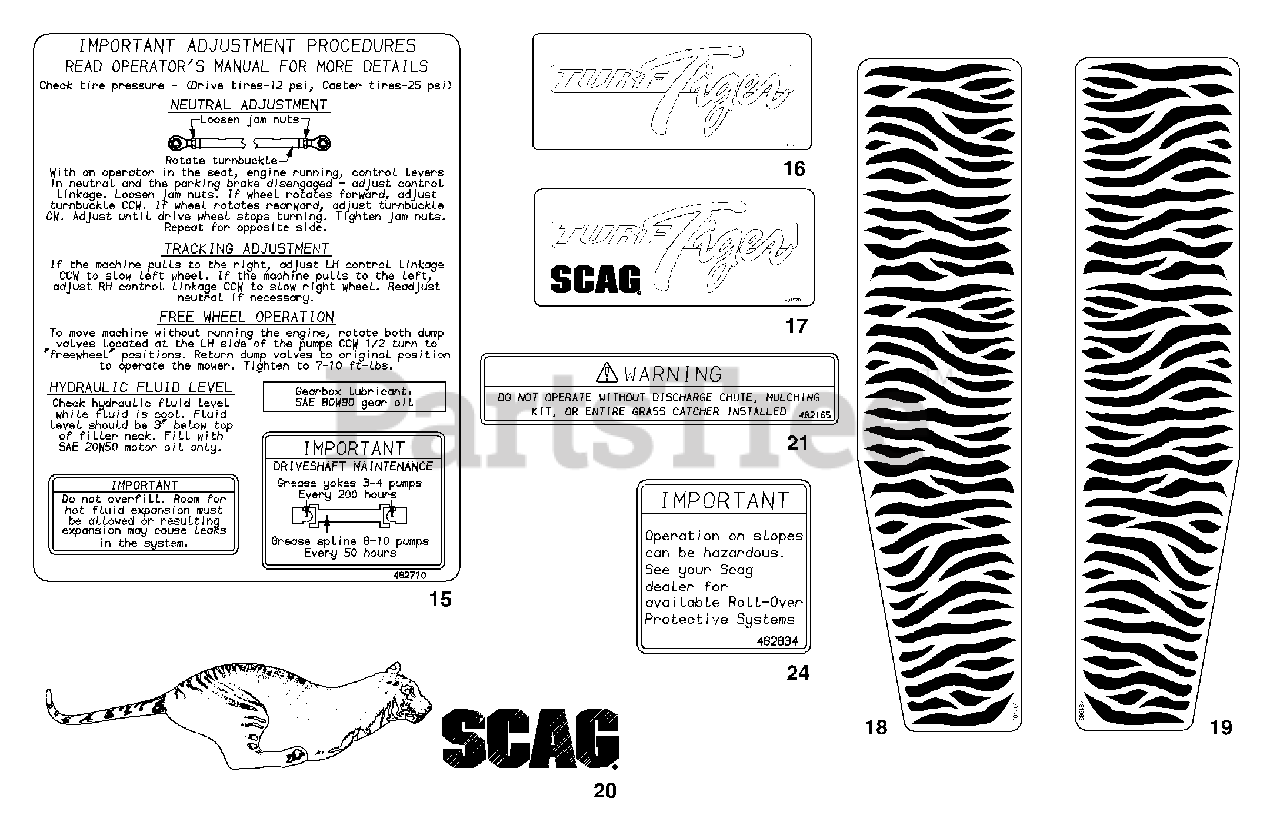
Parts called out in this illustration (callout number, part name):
15	Decal, Seat Support
16	Decal, Turf Tiger
17	Decal, Turf Tiger
18	Decal, Stripes-RH
19	Decal, Stripes-LH
20	Decal, Tiger
21	Decal, Warning
24	Decal, ROPS
